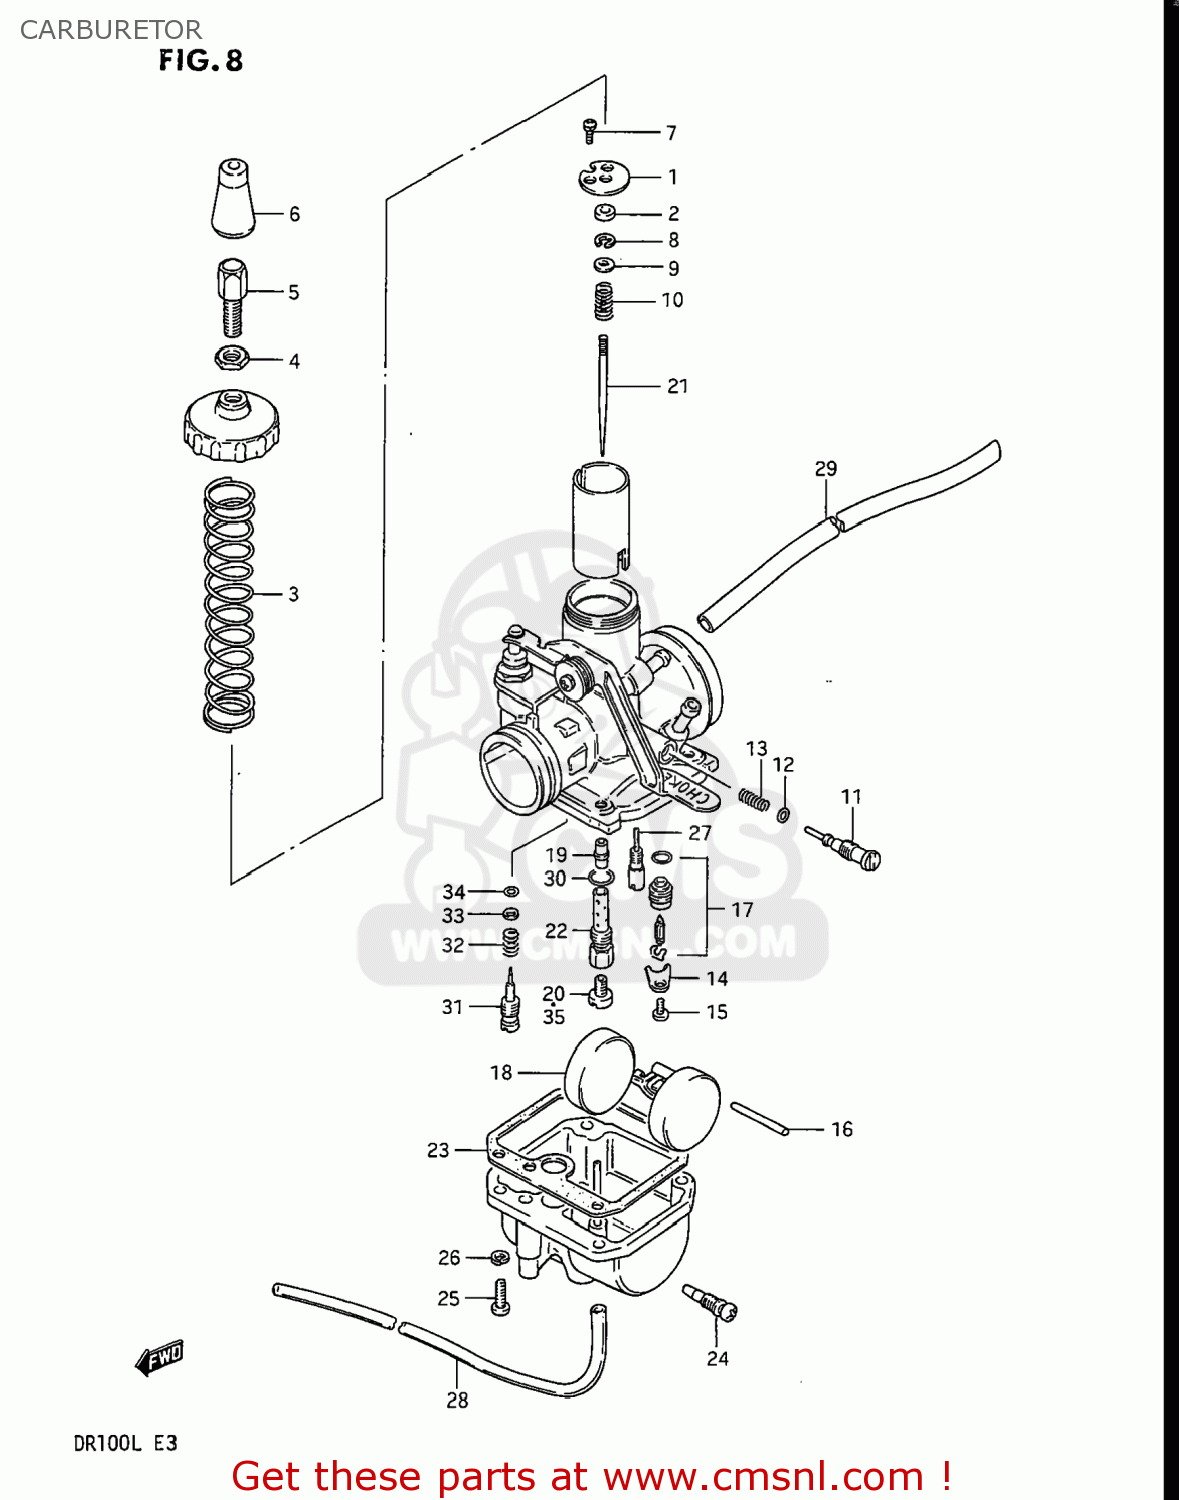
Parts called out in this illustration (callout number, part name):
1	PLATE,NEEDLE VALVE FITTING
2	RING
3	SPRING,THROTTLE VALVE
4	NUT
5	ADJUSTER,CABLE
6	CAP,RUBBER
7	SCREW
8	CLIP
9	WASHER,JET NEEDLE
10	SPRING
11	SCREW,THROTTLE STOP
12	O RING
13	SPRING
14	PLATE,NEEDLE VALVE FITING
15	SCREW
16	PIN,FLOAT
17	VALVE ASSEMBLY,NEEDLE
18	FLOAT
19	JET,NEEDLE
20	JET,MAIN(87.5)
21	NEEDLE,JET(5L8-3)
22	PIPE,BLEEDER
23	GASKET,FLOAT CHAMBER
24	PLUG,DRAIN
25	SCREW
26	LOCK WASHER
27	JET,PILOT(22.5)
28	HOSE
29	HOSE
30	O RING
31	SCREW,PILOT
32	SPRING
33	WASHER
34	O RING,PILOT AIR SCREW
35	JET,MAIN
